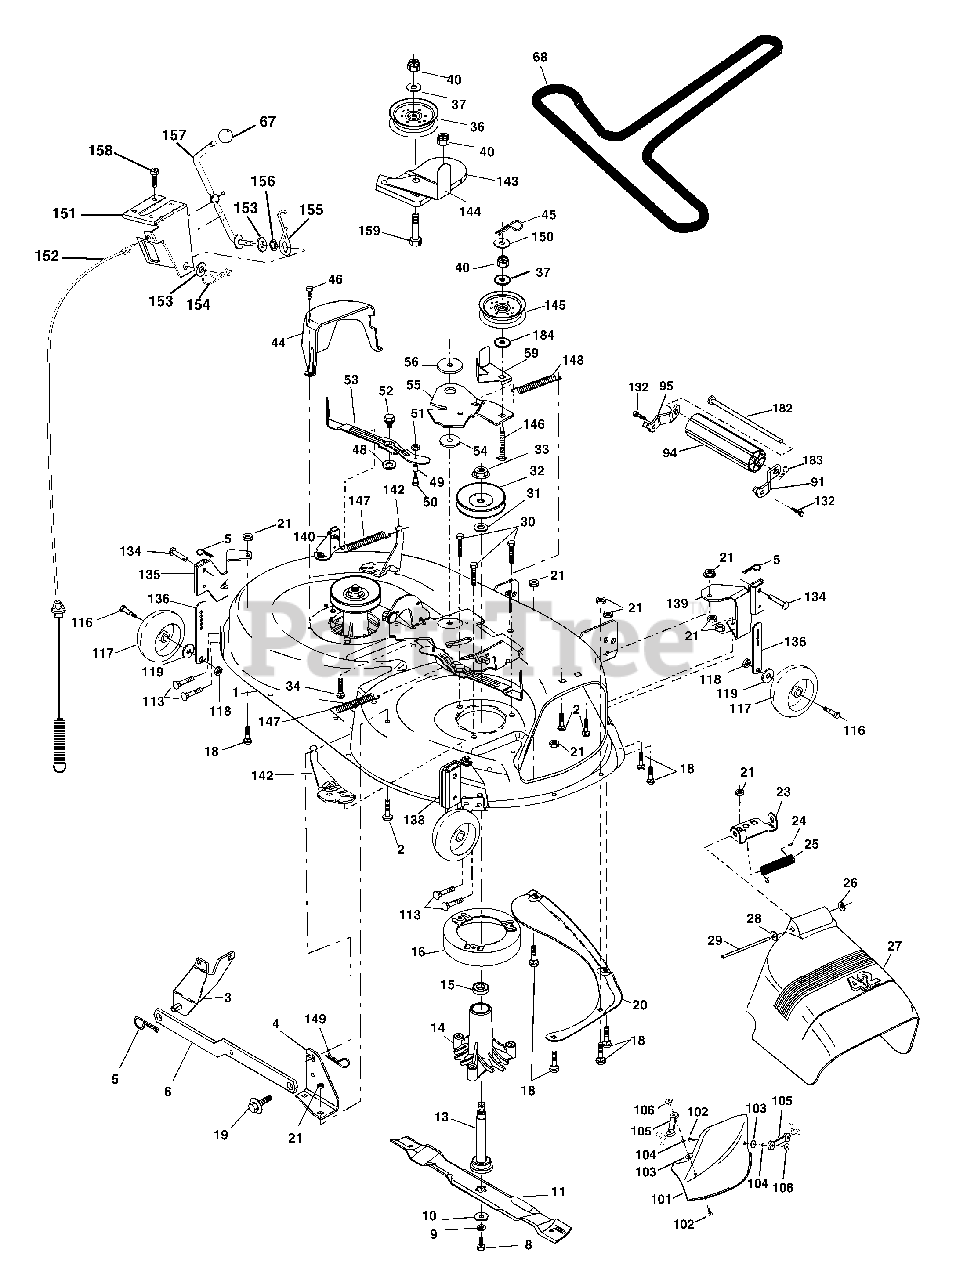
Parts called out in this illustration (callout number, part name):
1	Mower Deck Assembly, 42"
2	Bolt
3	Bracket Asm Fr. Sway Bar 3/42
4	Bracket Asm Deck 42" Sway Bar
5	Retainer Spring
6	Bar Sway Deck
8	Bolt 3/8-24 x 25 Grade 8 patched
9	Washer, Lock
10	Washer, Hardened
11	Blade, 42" Mulching Std
11	Blade, 42" Mulching Premium
11	Blade, 42" Hi-Lift
13	Shaft Assembly, Mandrel, Vented
14	Housing, Mandrel, Vented
15	Bearing, Ball, Mandrel
16	Stripper, Vented Mower Deck
18	Bolt, Carriage 5/16-18 x 5/8
19	Bolt, Shoulder
20	Baffle, Vortex
21	Nut
23	Bracket, Deflector Mower 42"
24	Cap, Sleeve 80 x 112 Blk Mower
25	Spring, Torsion, Deflector 2 52
26	Nut, Push Phos & Oil
27	Shield, Deflector 42" Blk
28	Washer 11/32 x 5/8 x 16 Gauge
29	Rod, Hinge 42" 6 75 W/G
30	Screw Thdrol Washer Head
31	Washer, Spacer Mower Vented
32	Pulley, Mandrel
33	Nut, Toplock Flange
34	Bolt
36	Pulley, Idler, Flat
37	Washer 13/32 x 13/16 x 16 Gauge
40	Nut
44	Guard, Mandrel, LH
45	Retainer
46	Screw, Thdrol 1/4-20 x 5/8 T
48	Washer, Hardened
49	Roller Assembly, Cam Follower
50	Bolt, Shoulder #10-24 Grade 5
51	Locknut
52	Bolt, Shoulder 5/16-18 UNC
53	Arm Assembly, Pad, Brake
54	Washer, Hardened
55	Arm, Idler
56	Spacer, Retainer
59	Guard TUV Idler
67	Knob
68	V-Belt, 42" Mower
91	Bracket Noseroller LH
94	Roller Nose
95	Bracket Noseroller RH
101	Cover Mulching
102	Screw 10-24 x 5/8
103	Washer #10
104	Washer Lock #10
105	Latch Asm.
106	Nut Weld
113	Screw 5/16-18 x 3/4
116	Bolt Shoulder 3/8-16 x 3-5/8
117	Wheel Gauge
118	Nut 3/8-16
119	Washer 3/8 x 7/8 x 14 Ga.
132	Screw 3/8-16 x 3/4
134	Pin Head Rivet
135	Bracket Asm. LH Rear
136	Bar Adjusting
138	Bracket Asm. RH Rear
139	Bracket Asm. RH Front
140	Bracket Asm. LH Front
142	Arm Spring Brake Mower
143	Bracket Arm Idler 42"
144	Keeper Belt 42" Clutch Cable
145	Pulley Idler Flat
146	Bolt Carriage Idler
147	Spring Extension
148	Spring Return Idler
149	Retainer Spring Yellow
150	Washer 9/32 x 3/4 x 16 Ga.
151	Bracket Clutch Cable
152	Clutch Cable 42"
153	Washer Flat 3/8" Type B
154	Spring Retainer
155	Spring Retention LVR CLTCH CAB
156	Spacer Clutch Cable
157	Rod Clutch Cable 3/8"
158	Screw Hex Thd Cut 1/4-20 x 1/2
159	Bolt Rdhd Sqn 3/8-16 UNC x 1-3/4
182	Rod Roller Nose
183	Retainer Spring
184	Washer 13/32 x 7/8 x 10 Ga.
